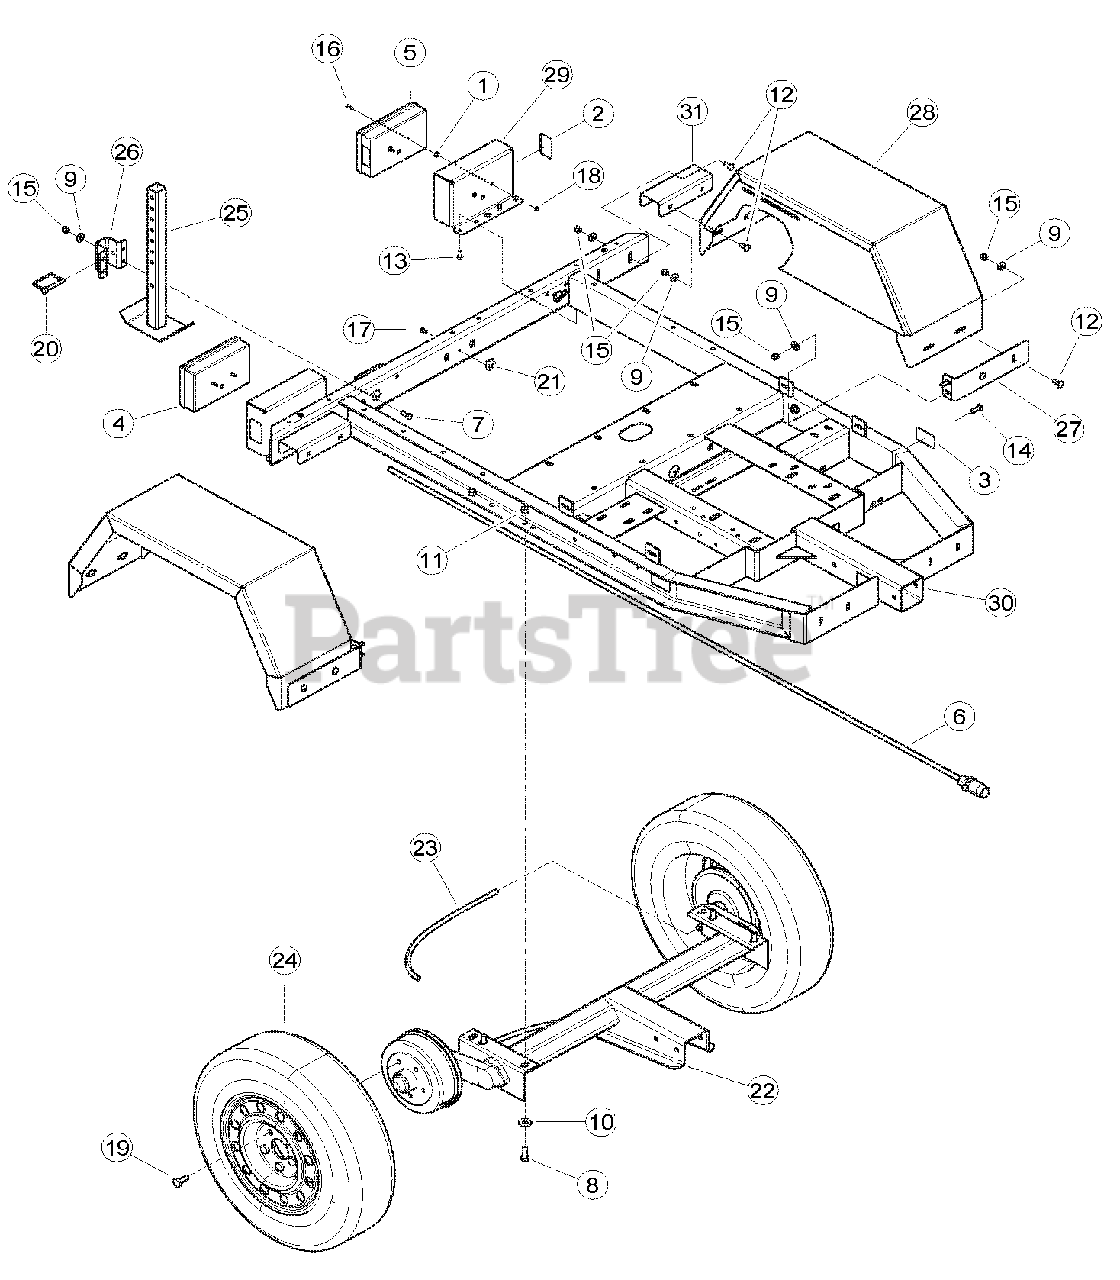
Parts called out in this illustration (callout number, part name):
1	GROMMET, 1/4 X 5/8 RUBBER
2	REFLECTOR, WIDE ANGLE RED
3	REFLECTOR, WIDE ANGLE AMBER
4	LIGHT, TAIL RH
5	LIGHT, TAIL LH
6	HARNESS, TRAILER LIGHTING
7	BOLT, 3/8 X 1 HEX HD GR5 ZP
8	BOLT, 1/2 X 1-1/4 HEX HD GR5 NC ZP
9	WASHER, 3/8 FLAT ZP
10	WASHER, 1/2 FLAT ZP
11	NUT, 1/2 CENTERLOCK GRB ZP
12	BOLT, 3/8 X 1 CRG GR5 NC ZP
13	SCREW, 11/32 X 7/8 HWH AB THREAD ZP
14	BOLT, 3/8 X 1-1/4 CRG GR5 NC ZP
15	NUT, 3/8 NE NYLOCK ZP
16	BOLT, 10-24 X 3/4 HEX HD GR8 PLAIN
17	RIVET, AL BLIND 1/4 X 3/4 DOME HEAD
18	NUT, #10-24 K-LOCK ZP
19	BOLT, 12MM LUG FOR WHEELS
20	PIN, 3/8" X 2-3/4" SNAP
21	CLAMP, CABLE MOUNT
22	AXLE, TORSION W/ BRAKES (VIN # 5VJAA0016CW003427 AND ABOVE)
23	CABLE, AXLE BRAKES SHORT
24	WHEEL/TIRE, P205/65R15
25	WELDMENT, REAR STABILIZER
26	GUIDE, TRAILER SUPPORT
27	BRACKET, FENDER
28	WELDMENT, CHIPPER FENDER
29	BRACKET, TAIL LIGHT
30	WELDMENT, CHIPPER TRAILER
31	PLATE, FENDER SPACER
